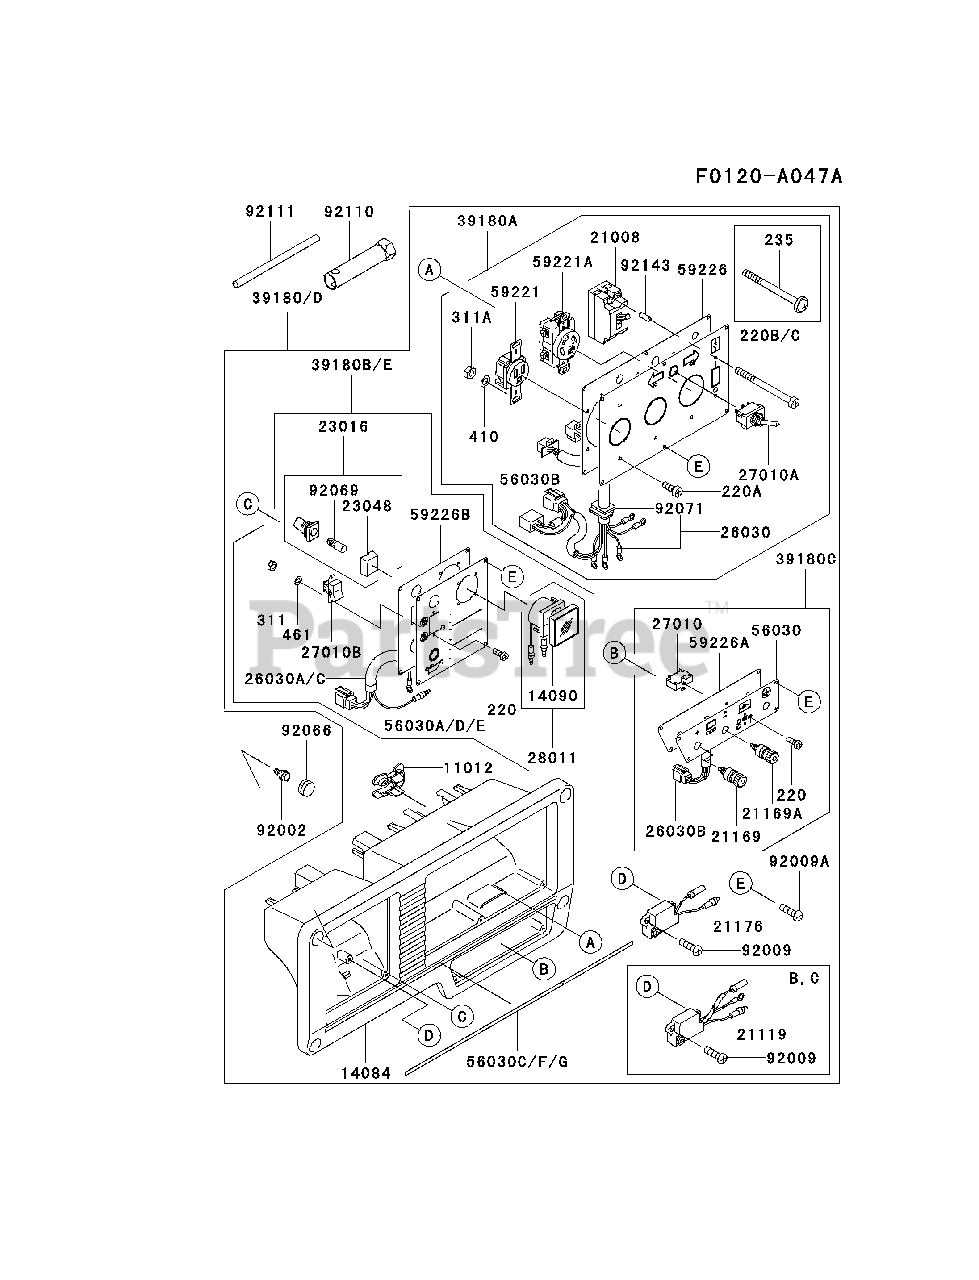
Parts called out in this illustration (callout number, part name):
220	SCREW-PAN-CROS
220A	SCREW-PAN-CROS
220B	SCREW-PAN-CROS
311	NUT-HEX
311A	NUT-HEX
410	W-PLAIN-S
461	WASHER-SPRING
92110	TOOL-WRENCH,21
